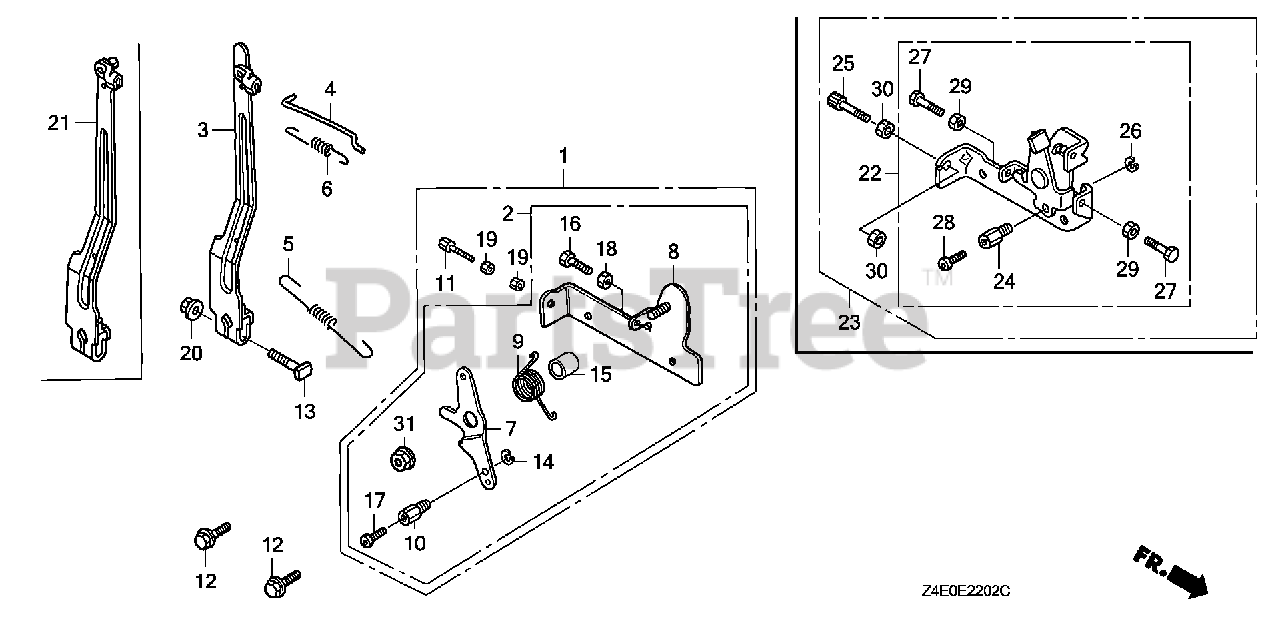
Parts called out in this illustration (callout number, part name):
2	CONTROL ASSY. (BOMAG)
3	ARM, GOVERNOR
4	ROD, GOVERNOR
5	SPRING, GOVERNOR
6	SPRING, THROTTLE RETURN
7	LEVER, CONTROL (REMOTE)
8	BASE, CONTROL (REMOTE)
9	SPRING, CONTROL LEVER RETURN
10	HOLDER, WIRE
12	BOLT, FLANGE (6X14)
13	BOLT, GOVERNOR ARM
14	CIRCLIP (5MM) Use from Engine SN 2327377.
15	COLLAR, CONTROL LEVER
16	BOLT, HEX. (5X20)
17	SCREW, PAN (4X6)
18	NUT, HEX. (5MM)
20	NUT, FLANGE (6MM)
31	NUT, FLANGE (6MM)
